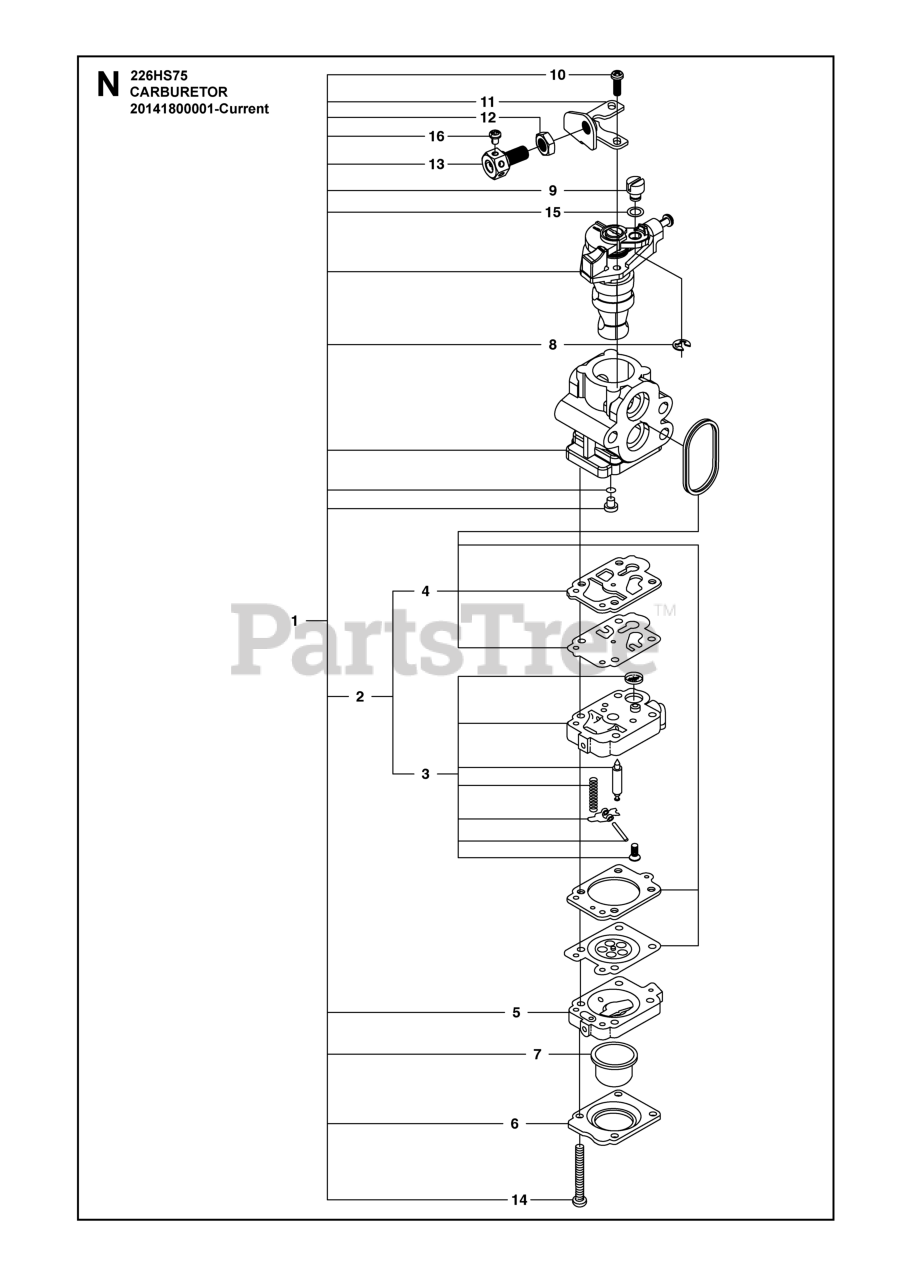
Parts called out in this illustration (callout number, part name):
1	CARBURETTOR ASSY
2	REBUILD KIT
3	CARBURETOR BODY
4	GASKET KIT
12	NUT
13	SCREW CABLE ADJUST
